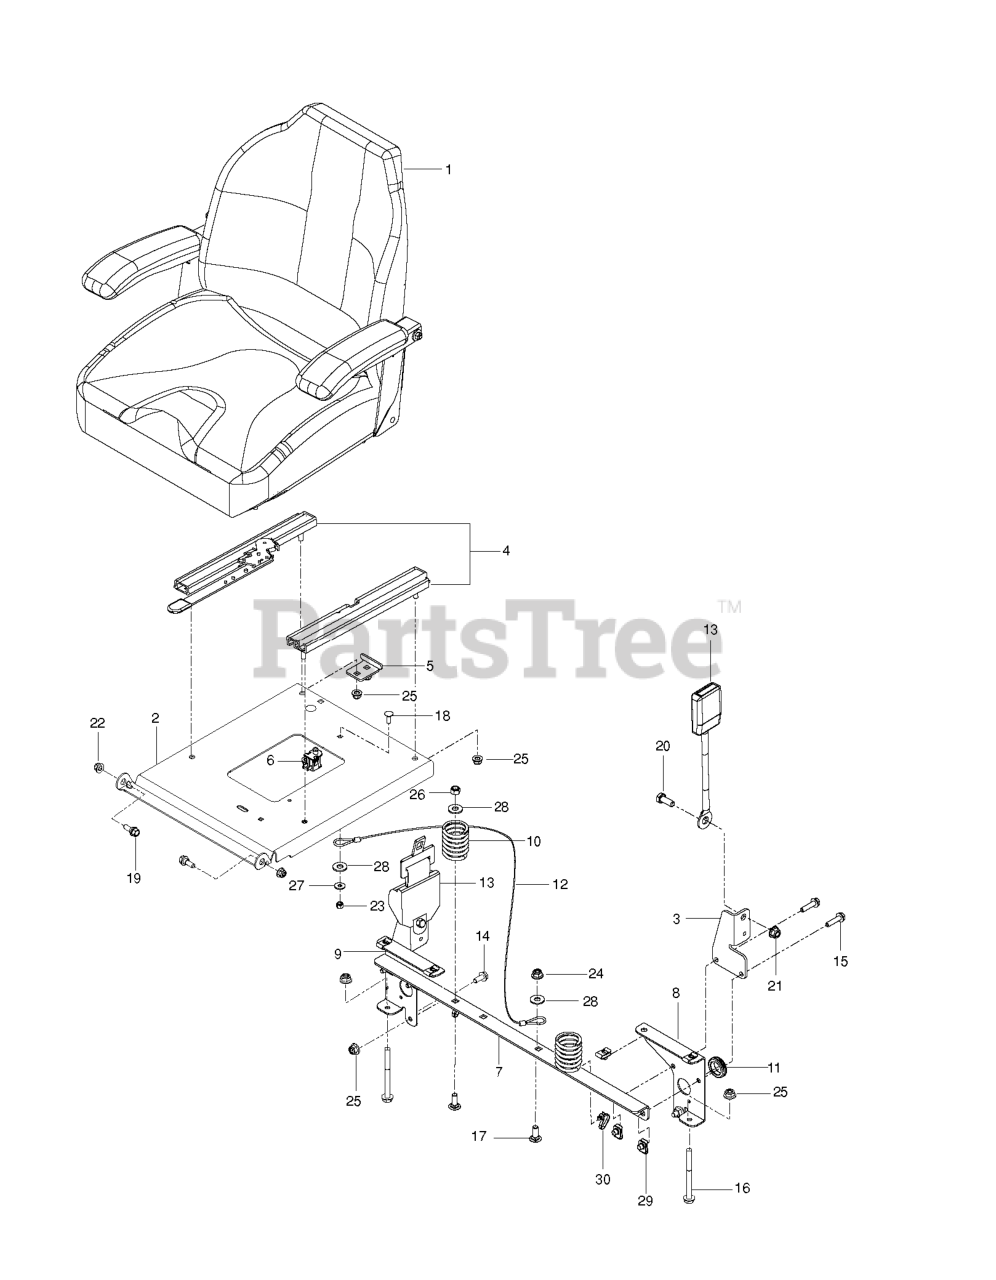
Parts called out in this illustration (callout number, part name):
1	SEAT.907.VINYL.HUSQVARNA
2	SUPPORT.PNT.SEAT.ORANGE
3	MOUNT.SEAT.BELT.BLACK
5	STOP, SEAT - BLACK
6	SEAT SWITCH
7	SUPPORT, SEAT
8	SUPPORT, RT, BLK
9	SUPPORT, LT, BLK
10	SPRING COMPRESSION
11	RUBBER GROMMET
12	SEAT LANYARD
13	SEAT BELT, RETRACTABLE
14	HHFS 5/16-18 X 3/4
15	HHFS 5/16-18 X 1.25 TPBLT GD 5
16	BOLT.HEX.FLNG.5/16-18X3.75
17	BOLT D
18	BOLT
19	SB 5/16-18 HEX HD GD5, BLK ZN
20	SCREW 7/16-20 X 1 HHB GR5
21	NUT HEX 7/16F LOCK RP
22	NUT.71038.31-18.HEX.NYLOCK
23	LOCKNUT.NYLOC.1/4-20
24	NUT 3/8-16 HEX FLG NYLOC ZD
25	5/16-18 NYLOC FLANGE NUT
26	NUT
28	RP WASHER 3/8 FLAT
29	U-CLIP 5/16-18 NUT RETAINER
30	TIE WRAP, 8-3/8", W/CLIP
